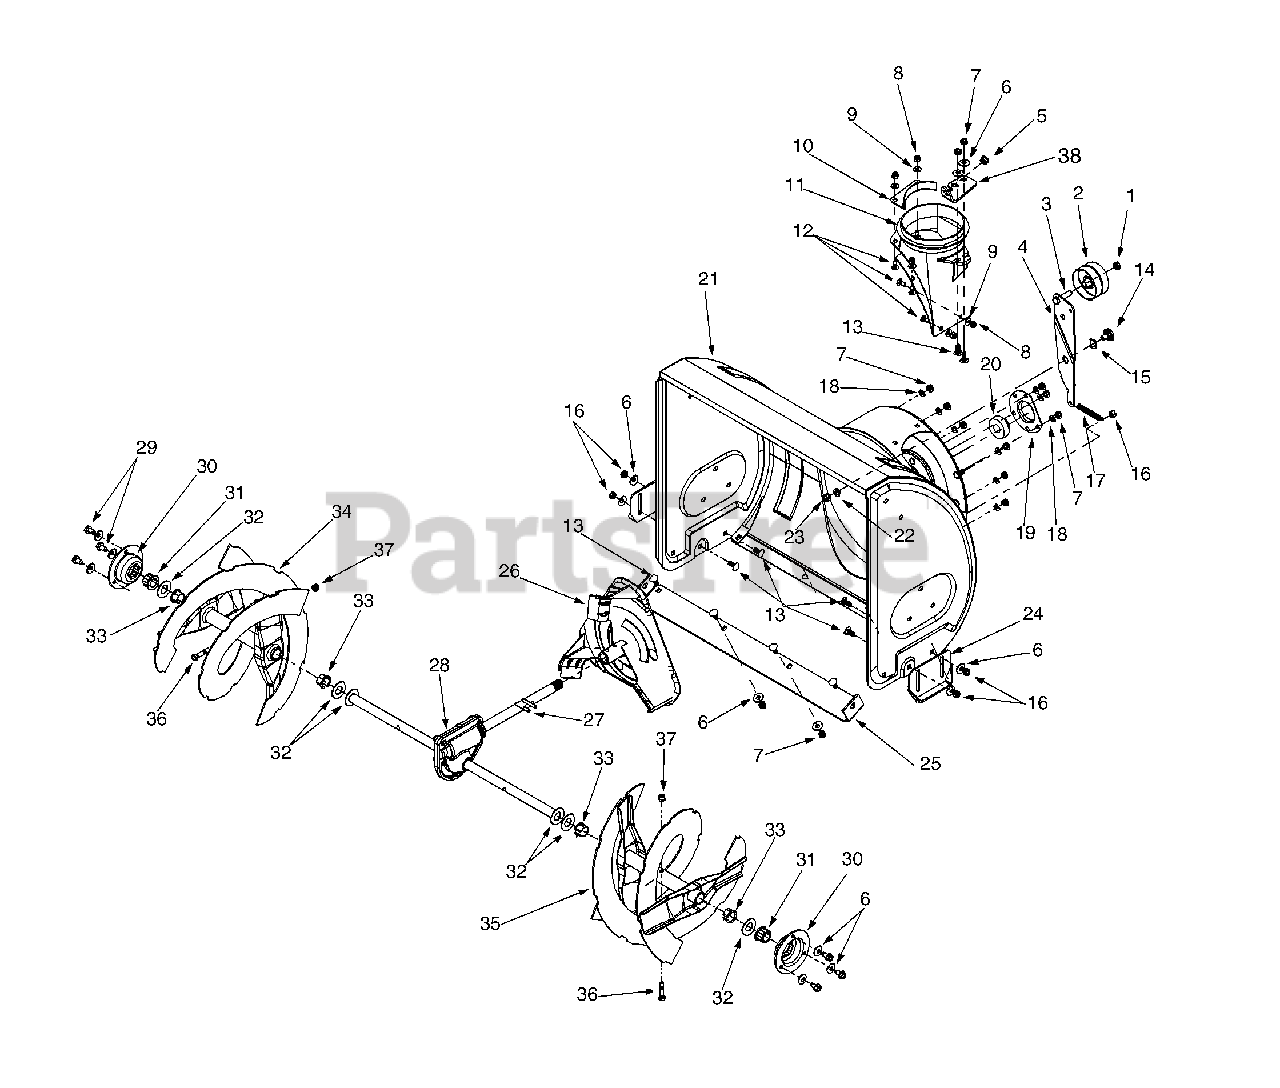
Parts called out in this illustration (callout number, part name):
1	Lock Jam Nut 3/8-24
2	Flat Idler
4	Hex Cap Screw 3/8-24 x 1.50
5	Bushing
6	Bell Washer
7	Hex Nut 5/16-18
8	Hex Lock Nut 1/4-20
9	Flat Washer
11	Chute Adapter
12	Carriage Screw 1/4-20 x .62
13	Carriage Bolt 5/16-18
14	Shoulder Screw
15	Wave Washer
16	Hex Nut 5/16-18
17	Extension Spring
18	Lock Washer 5/16
19	Bearing Housing
20	Ball Bearing
23	Hex Nut 3/8-16
28	24" Gear Assembly
29	Hex Washer Screw 5/16-18
31	Hex Flange Bearing
32	Flat Washer
33	Flange Bushing
37	Lock Nut 5/16-18
